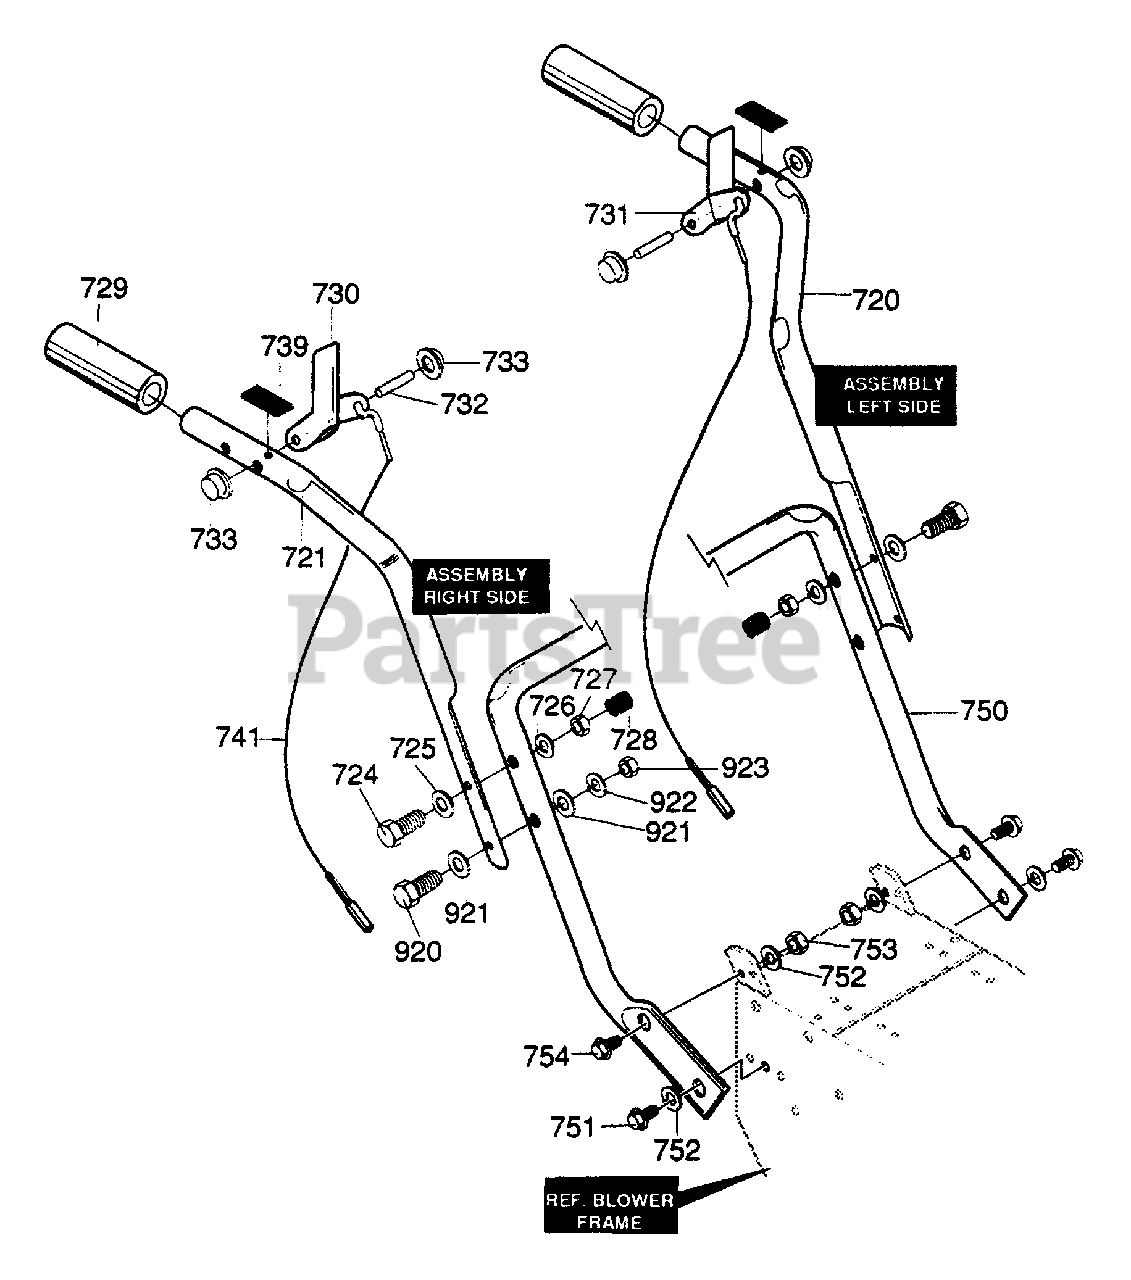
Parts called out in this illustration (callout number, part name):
720	HANDLE, UPPER, LH
721	HANDLE, UPPER, RH
724	SCREW, 3/8-16x3.00 HHCFT
725	FLATWASHER, .406x.81 x.065
726	WASHER, REGSPTLK.393x.68x.10
727	NUT, 3/8-16 REGHXCTRLK
728	STOP, PLASTIC.375
729	GRIP, HANDLE 1.25x4.38
730	HANDLE, RH ASSEMBLY
731	HANDLE, LH ASSEMBLY
732	PIN, PIVOT.31 OD
738	NUT, PUSH ON CAP .312 OD
739	BUMPER, RECT W/FLAT TOP
741	CABLE, CLUTCH 31.75" TRACTION
750	HANDLE, LOWER
751	SCREW, 5/16-18x.75 HHC
752	WASHER, HVSPTLK.328x.60x.09
753	NUT, 5/16-18 REGHEX
754	SCREW, 5/16-18x.75 WAHHTAP
920	SCREW 3/8-16X2.00 IN.
921	FLATWASHER.406 X.81 X.065
922	WASHER, REGSPTLK
923	NUT, 3/8-16 REGHEXCTRLK
